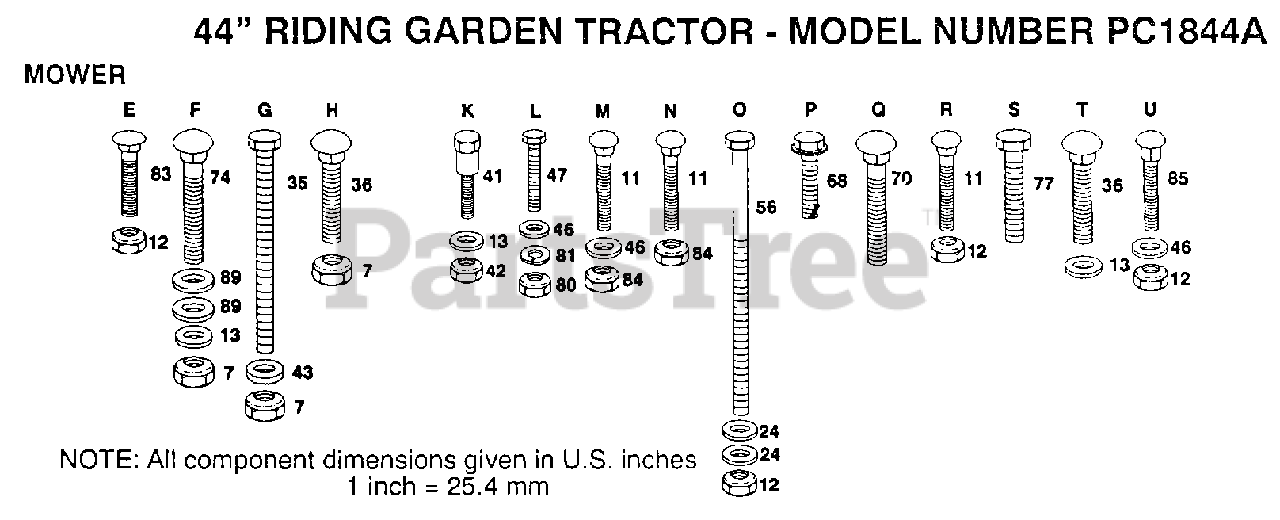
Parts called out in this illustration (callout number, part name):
11	BOLT
13	WASHER
24	WASHER M
35	BOLT - HEX 3/8 - 16 X 3
41	BOLT SHOULDER
42	LOCKNUT
43	WASHER
46	WASHER
56	BOLT
68	SCREW
70	BOLT
74	BOLT
77	BOLT
80	NUT.HEX.5/16-18
81	LOCKWASHER
83	BOLT
89	WASHER
